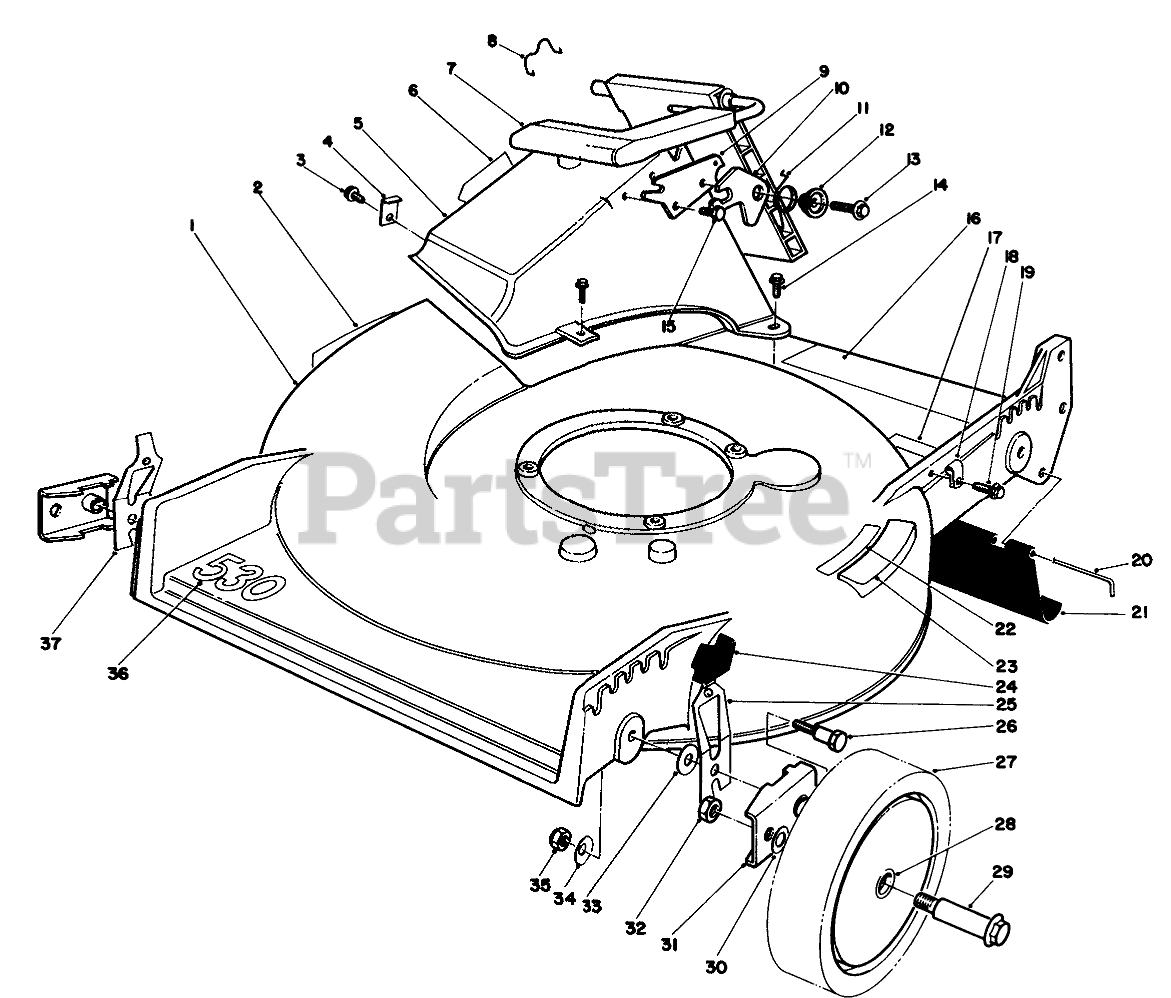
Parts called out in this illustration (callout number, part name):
1	Housing (Incl. Ref. #2)
2	DECAL-DANGER
3	SCREW
4	TUNNEL CLIP
5	Tunnel Discharge
6	Decal-Attention
7	Discharge Door Assembly
8	DOOR RET SPRING
9	DOOR LATCH PLATE
10	SAFETY LATCH
11	TORSION SPRING
12	DOOR SPACER
13	SCREW-HWH
14	SCREW-HWH
15	SCREW-PLASTITE
16	Danger-Decal
17	Decal
18	CLAMP-CABLE
19	SCREW
20	ROD-SHIELD
21	SHIELD-TRAILING
22	Decal-Place Foot Here
23	STEP PAD DECAL
24	KNOB-ARM
25	L. HP SPRING ARM ASM
26	PIVOT SCREW
27	Wheel & Tire Assembly (Inc. Ref. #28)
28	BUSHING
29	BOLT-WHEEL
30	WASHER
31	HP PIVOT ARM ASM
32	Nut
33	WASHER-PIVOT
34	WASHER-BELLEVILLE
35	NUT-LOCK, NI
36	Decal-530
37	R HP SPRING ARM ASM
